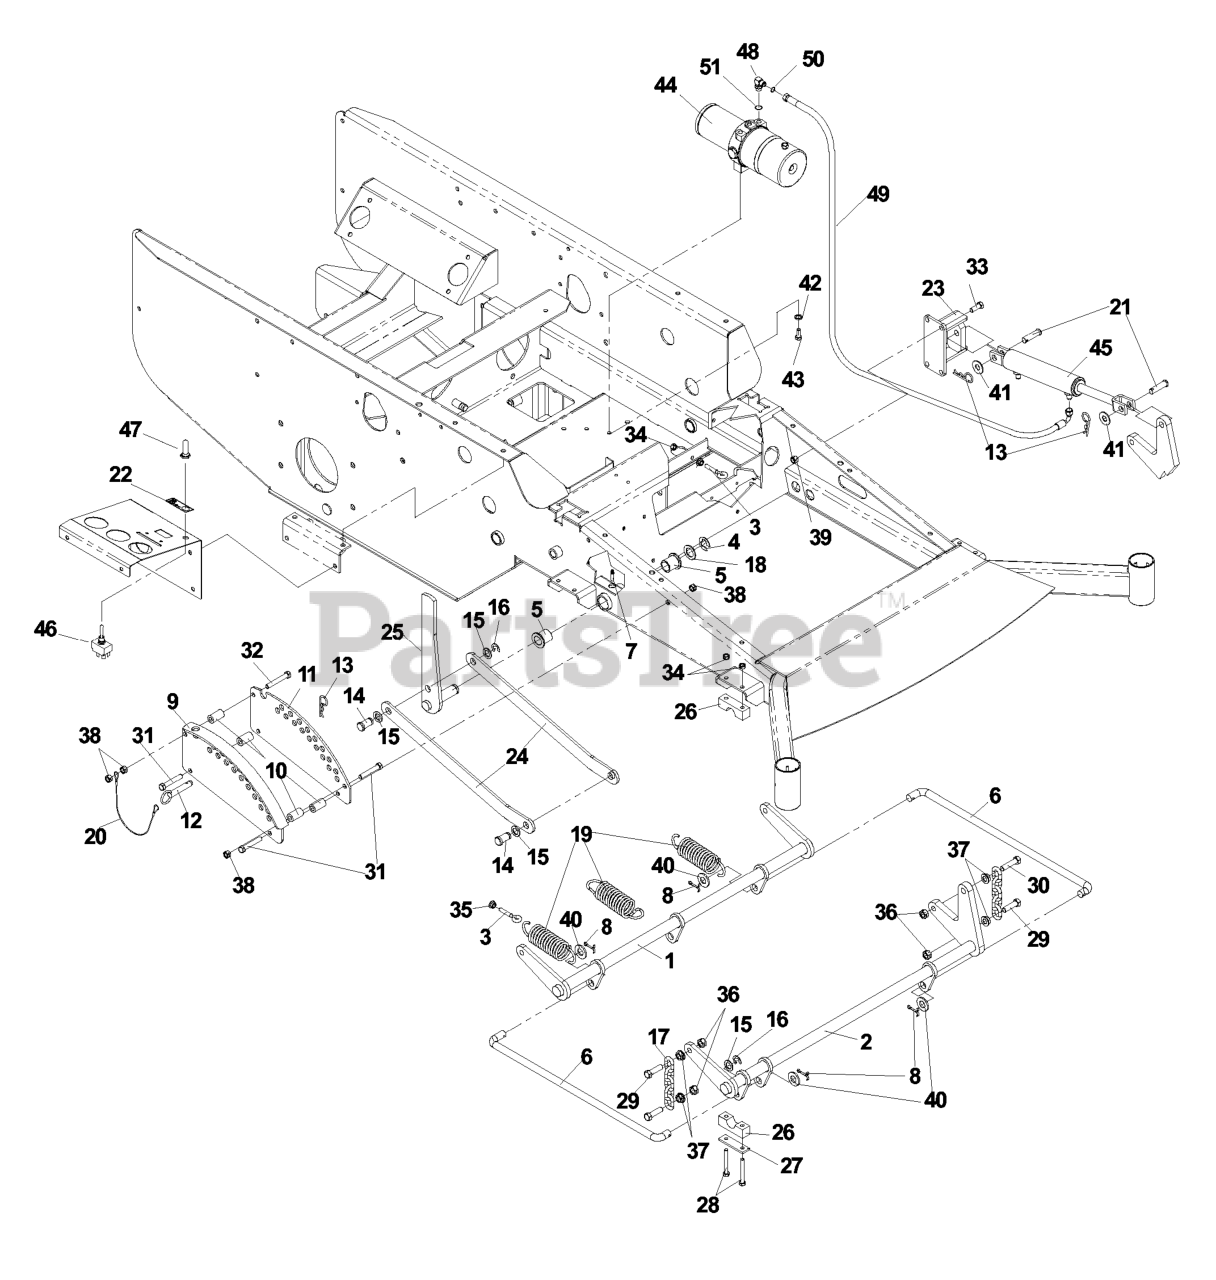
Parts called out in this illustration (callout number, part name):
1	SHAFT LIFT REAR
2	LIFT SHAFT WELDMT FRONT
3	EYEBOLT, RH
4	E-RING 7/8
5	BUSHING, FLANGED
6	CONNECTING LINK
7	GREASE ZERK LONG
8	COTTER PIN
9	ADJ. PLATE WLDMNT
10	DECK LIFT SPACER
11	ADJ. PLATE PAINTED
13	HAIRPIN #4
14	CLEVIS PIN
15	BUSHING
16	E-RING 5/8
17	LIFT CHAIN
18	BSHG .875 X 1.375 X .074 ZD
19	DECK LIFT SPRING
21	CLEVIS PIN 1/2 X 3/4
22	DECAL, LIFT SWITCH
23	CYLINDER MTG WLDMT
24	LIFT LINKAGE,PAINTED
25	LIFT LEVER
26	PILLOW BLOCK
27	REINFORCEMENT BAR
28	BOLT 5/16C X 2 1/2
29	HCS 7/16C X 1 1/2
30	HCS 7/16 - 14 X 1 3/4
31	HCS 3/8C X 2 1/4
32	HCS 3/8C X 2 1/2
33	HCS 3/8-16X1.GRD.5.ZD
34	NUT 5/16C CENTERLOCK
35	NUT 5/16C WHIZ
36	NUT 7/16C CENTERLOCK
37	NUT 7/16C WHIZ
38	NUT 3/8C CENTERBLOCK
39	NUT 3/8-16 NYLOC
40	WASHER 5/8 FLAT
41	WASHER 1/2 FLAT
42	SLW 3/8 STD
43	SCREW 3/8C X 3/4 HEX CAP
44	HYDRAULIC POWER UNIT
45	HYDRAULIC CYLINDER
47	SWITCH BOOT
49	HYDRAULIC HOSE ASSY
